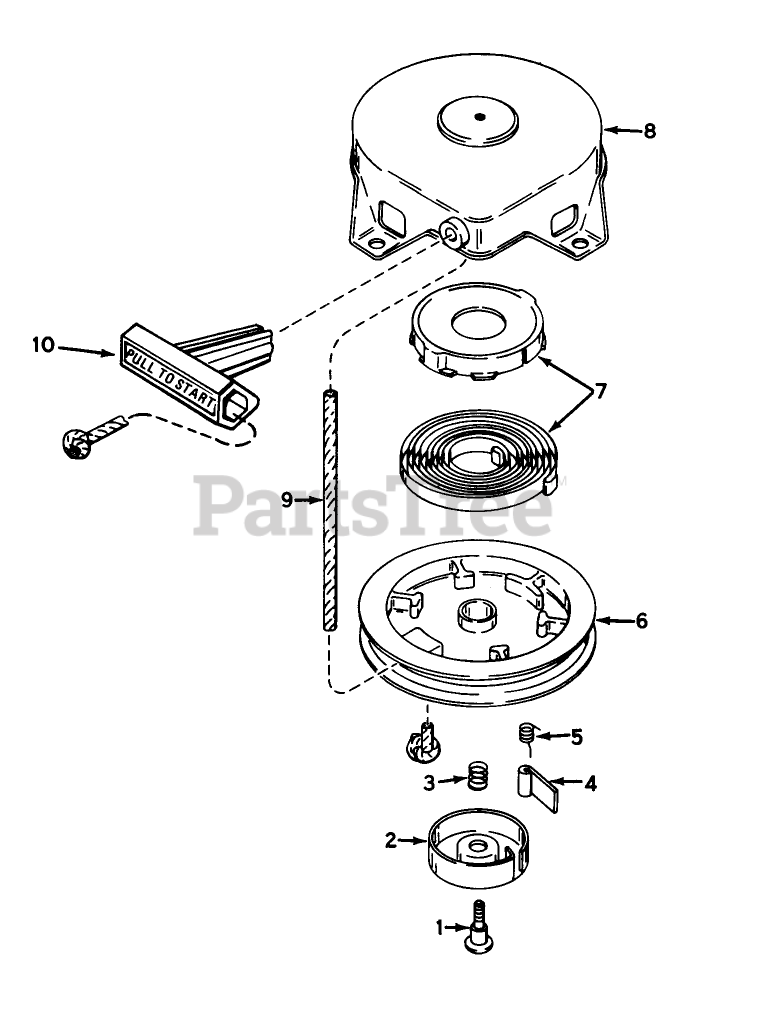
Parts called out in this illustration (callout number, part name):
2	Retainer
3	Spring-Brake
4	Dog-Starter
5	Spring-Dog
7	Spring & Keeper Assy
8	Housing-Starter
9	Rope-Starter (98 cut to length)
10	Handle-Starter
